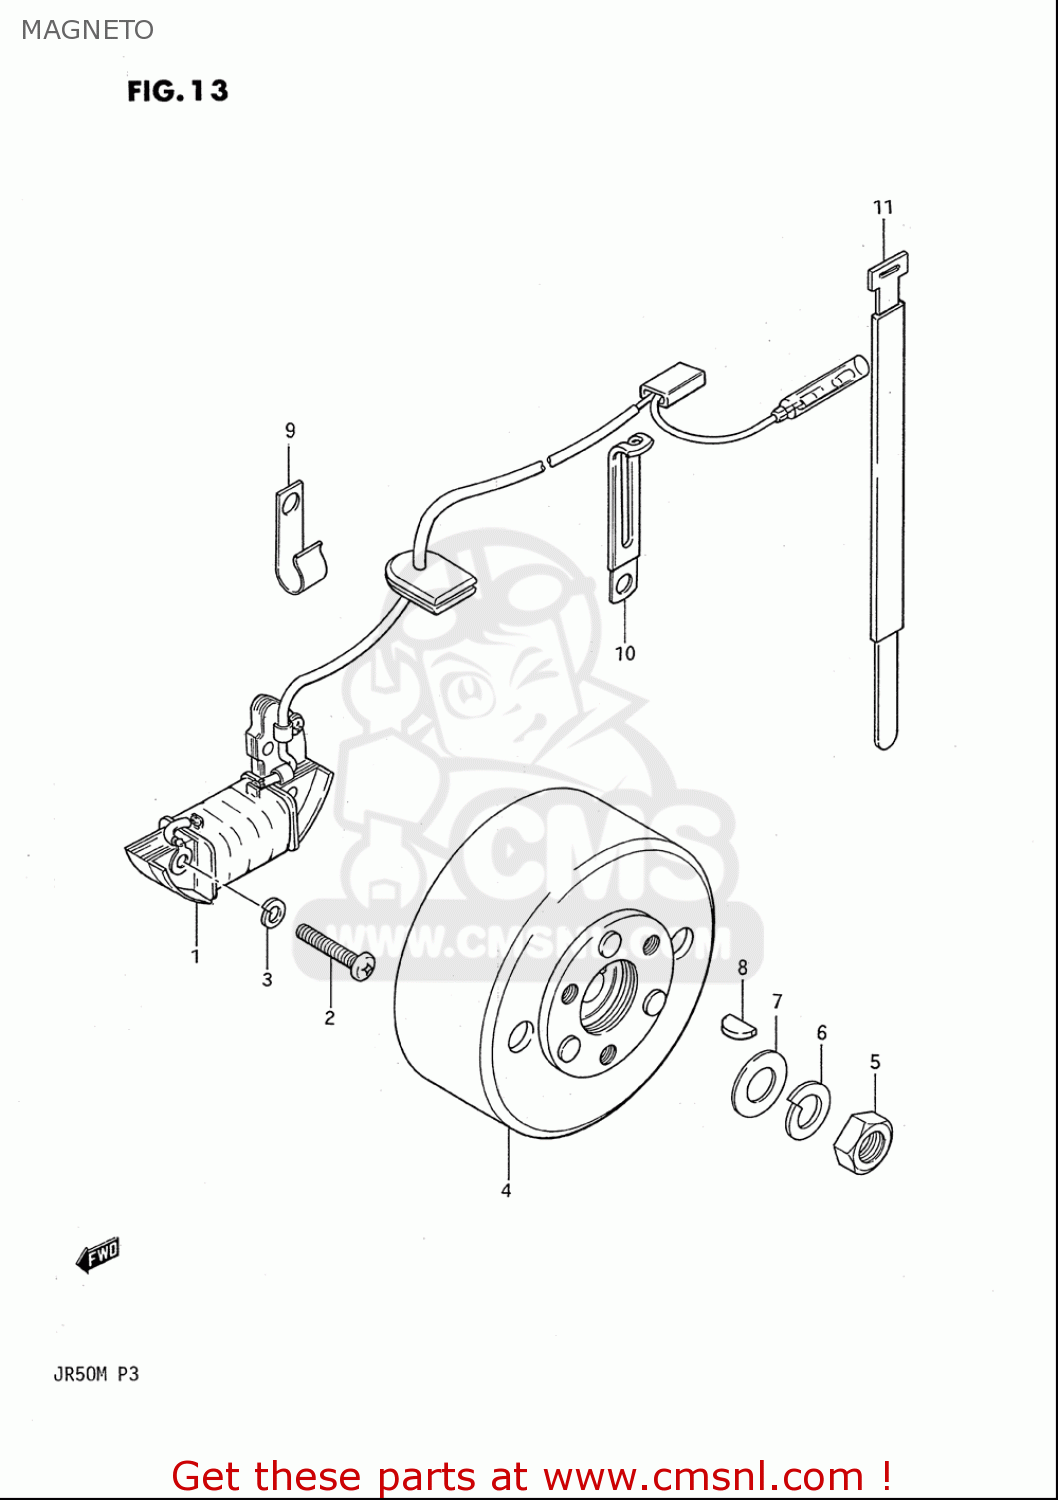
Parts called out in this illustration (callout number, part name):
1	COIL ASSY,IGNITION PRIMARY
2	SCREW
3	WASHER,LOCK
4	ROTOR ASSY
5	NUT
6	WASHER,LOCK
7	WASHER
8	KEY
10	CLAMP(L:65)
11	CLAMP
